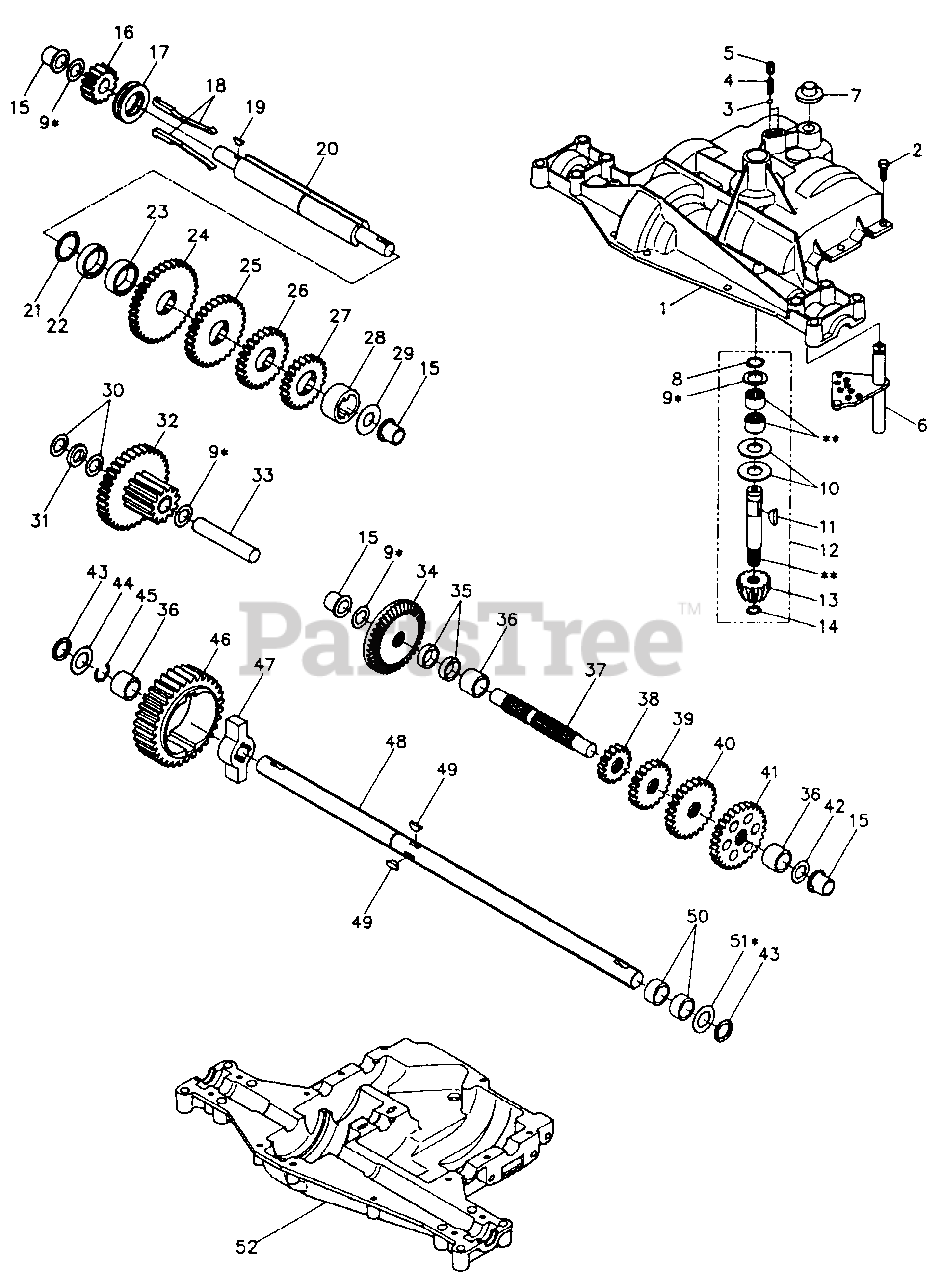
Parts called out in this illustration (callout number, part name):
1	Housing, Upper 3865A
2	Screw, Tapping, 1/4 - 20 x .734 LG. 1919
3	Ball, Detent 1151
4	Spring, Detent 3626
5	Screw, Set 3623
6	Shifter Assembly 4265
7	Boot, Shiner 5024
8	Ring, Retaining 1099
9	Washer, Plain, .632 x 1.00 x .010 1959
10	Washer, Plain, .632 x 1.38 x .046 3876
11	Key, Woodruff, #9 1374
12	Input Shatt Kit Assembly 4559
13	Pinion, Bevel, 14T 3590
14	Ring, Retaining 3624
15	Bearing, Flange 1542
16	Gear, Spur, 14T 3773
17	Collar, Clutch 3631
18	Key, Clutch 3828
19	Key, Woodruff, #3 1369
20	Shaft, Intermediate 3883
21	Ring, Retaining 3627
22	Spacer, 1.134 x 1.45 x .375 5029
23	Spacer, 1.134 x 1.45 x .494 3841
24	Gear, Spur, 35T 3785
25	Gear, Spur, 30T 3867
26	Gear, Spur, 25T 3783
27	Gear, Spur, 22T 3869
28	Spacer, 1.133 x 1.50 x .750 5026
29	Washer, Plain, .640 x 1.37 x .061 3628
30	Washer, Plain, .632 x 1.00 x .026 1423
31	Spacer, .630 x 1.00 x .169 3422
32	Gear. Comb. 12T & 35TAssembly 4286
33	Shatt, Idler 3967
34	Gear, Bevel, 42T 5012
35	Spacer .781 x 1.00 x .281 3630
36	Spacer .781 x 1.00 x .750 3684
37	Shaft Drive 5015
38	Gear Spur, 15T 3707
39	Gear, Spur, 20T 3866
40	Gear, Spur, 25T 3719
41	Gear, Spur, 28T 3868
42	Washer, Plain, .632 x 1.00 x .060 1145
43	Seal, Felt 3191
44	Washer, Plain, .758 x 1.25 x .040 3198
45	Ring, Retaining 5031
46	Gear, Spur, 32T 3839
47	Cross, Axle 5032
48	Axle 5030
49	Key, Wocdruff, #61 1375
50	Spacer, .781 x 1.00 x .494 5016
51	Washer, Plain, .758 x 1.25 x .020 3408
52	Housing, Lower 3864B
